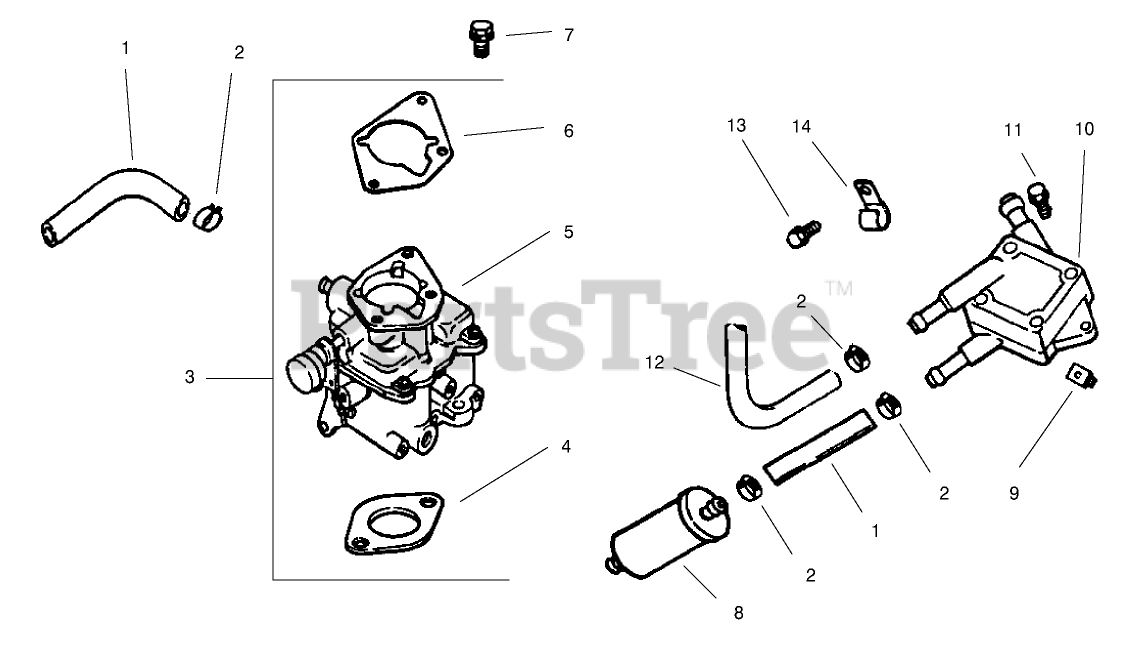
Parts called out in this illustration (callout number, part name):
1	Line-Fuel 9"
2	CLAMP-HOSE, SPRING (1/2)
3	Kit-Carburetorw/Gasket (Includes 4-6)
4	Gasket-Carburetor
5	Carburetor ASM (Includes 25 757 01-S, 24 757 02-S, 24 757 03-S, & 24 757 07-S)
6	GASKET-BASE, AIR CLEANER
7	SCREW-FLANGE (M6X1.0X30)
8	Filter-Fuel
9	Nut-Plastic
10	PUMP-FUEL
11	SCREW-TAP (M6X1.7X18)
12	Line-Fuel, Flexible (15.5)
13	Screw-HF (M6x1.0x12)
14	CLIP-CABLE
